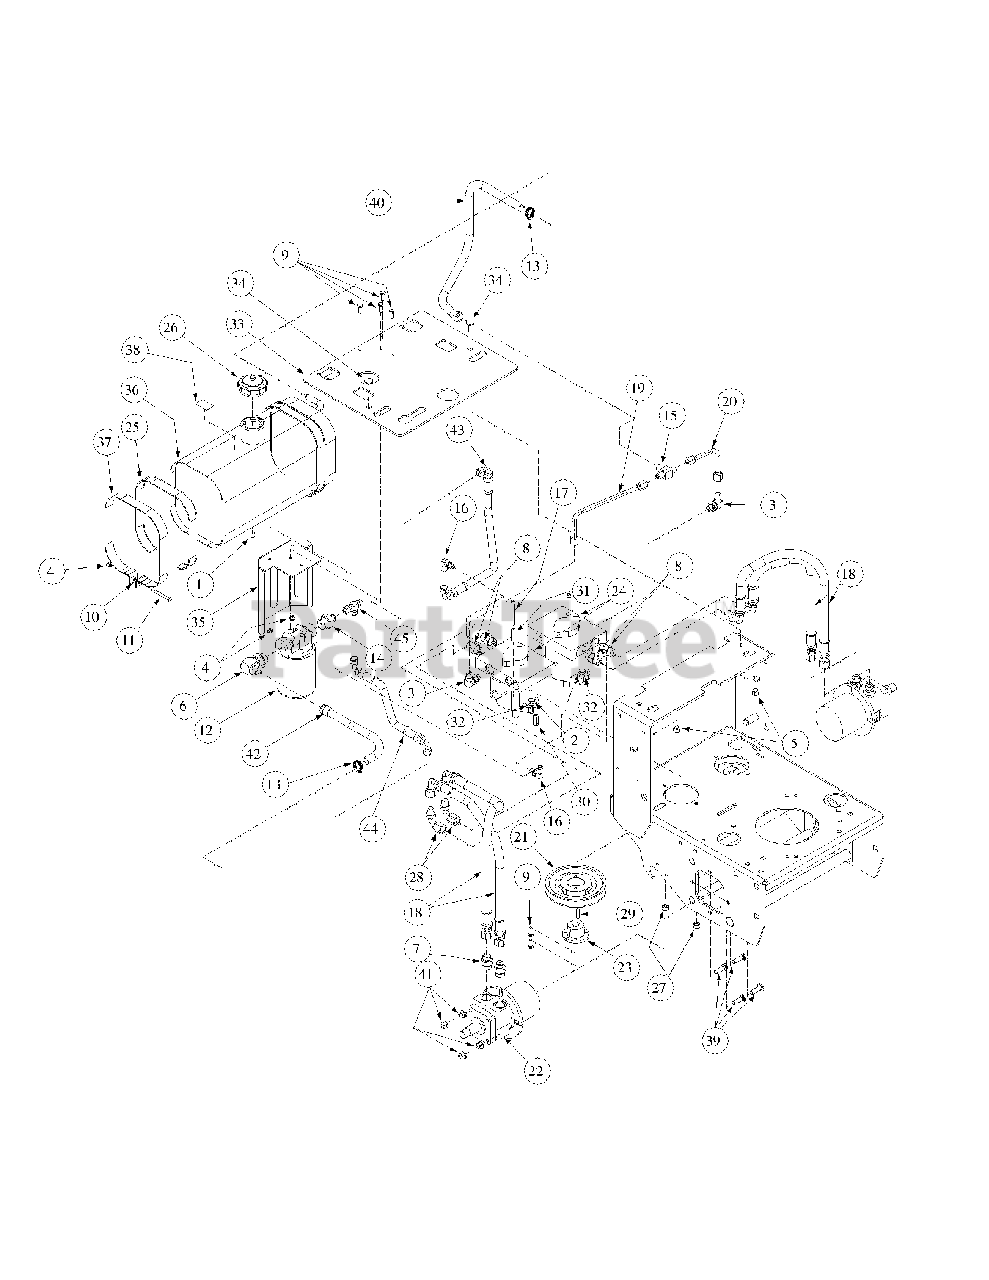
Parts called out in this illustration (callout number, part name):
1	Plug, 1/4"
2	Cap Screw, Standard, 3/8-16 x 1-1/4
3	Fitting, Aeroquip
4	Lock Nut, 1/4-20
5	Lock Nut, 3/8-16
6	Elbow 90° 1/2 x 3/4
7	Fitting, Aeroquip
8	Fitting, Aeroquip
9	Cap Screw, 1/4-20 x 3/4
10	Hex Nut, 1/4-20
11	Machine Screw, 1/4-20 x 2, Zinc
12	Filter Head 3/4
12	Oil Filter
13	Clamp Wormgear, 5/16-7/8
14	Straight Connector 1/2 x 3/4
15	Fitting Aeroquip
16	Fitting, Aeroquip
17	Cap Screw, Socket Head, 1/4-20 x 2-1/2 Zinc
18	Hydro Hose Assembly, Reverse Pressure
19	Hydraulic Line, Pump Return Long
20	Hydraulic Line, Pump Return Short
21	Deck Pulley
22	Hydraulic Motor, Wheel
23	Bushing, 15mm Bore, Split, Type "D"
24	Pump Hydro BDP10L117
25	Pad, Oil Tank
26	Cap, Hydraulic Oil Tank
27	Lock Nut, 3/8-16
28	Fitting Aeorquip
29	Pump Key
30	Nut, Pump Release
31	Spacer, Pump Release
32	Washer, Idler
33	Fuel Tank, Mounting Plate
34	Carriage Bolt, 3/8-16 x 2
35	Filter Guard
36	Oil Tank w/Neck
37	Oil Tank Strap
38	Oil Label, 20W-50
39	Carriage Bolt, 3/8-16 x 1.25
40	Hose Assembly
40	Hose Hydraulic 22"
41	Hex Nut, Flange Lock, 3/8-16
42	Hose, Filter to Tank
43	Hose, Filter to Left Pump
44	Hose, Filter to Right Pump
45	Fitting, Aeroquips
